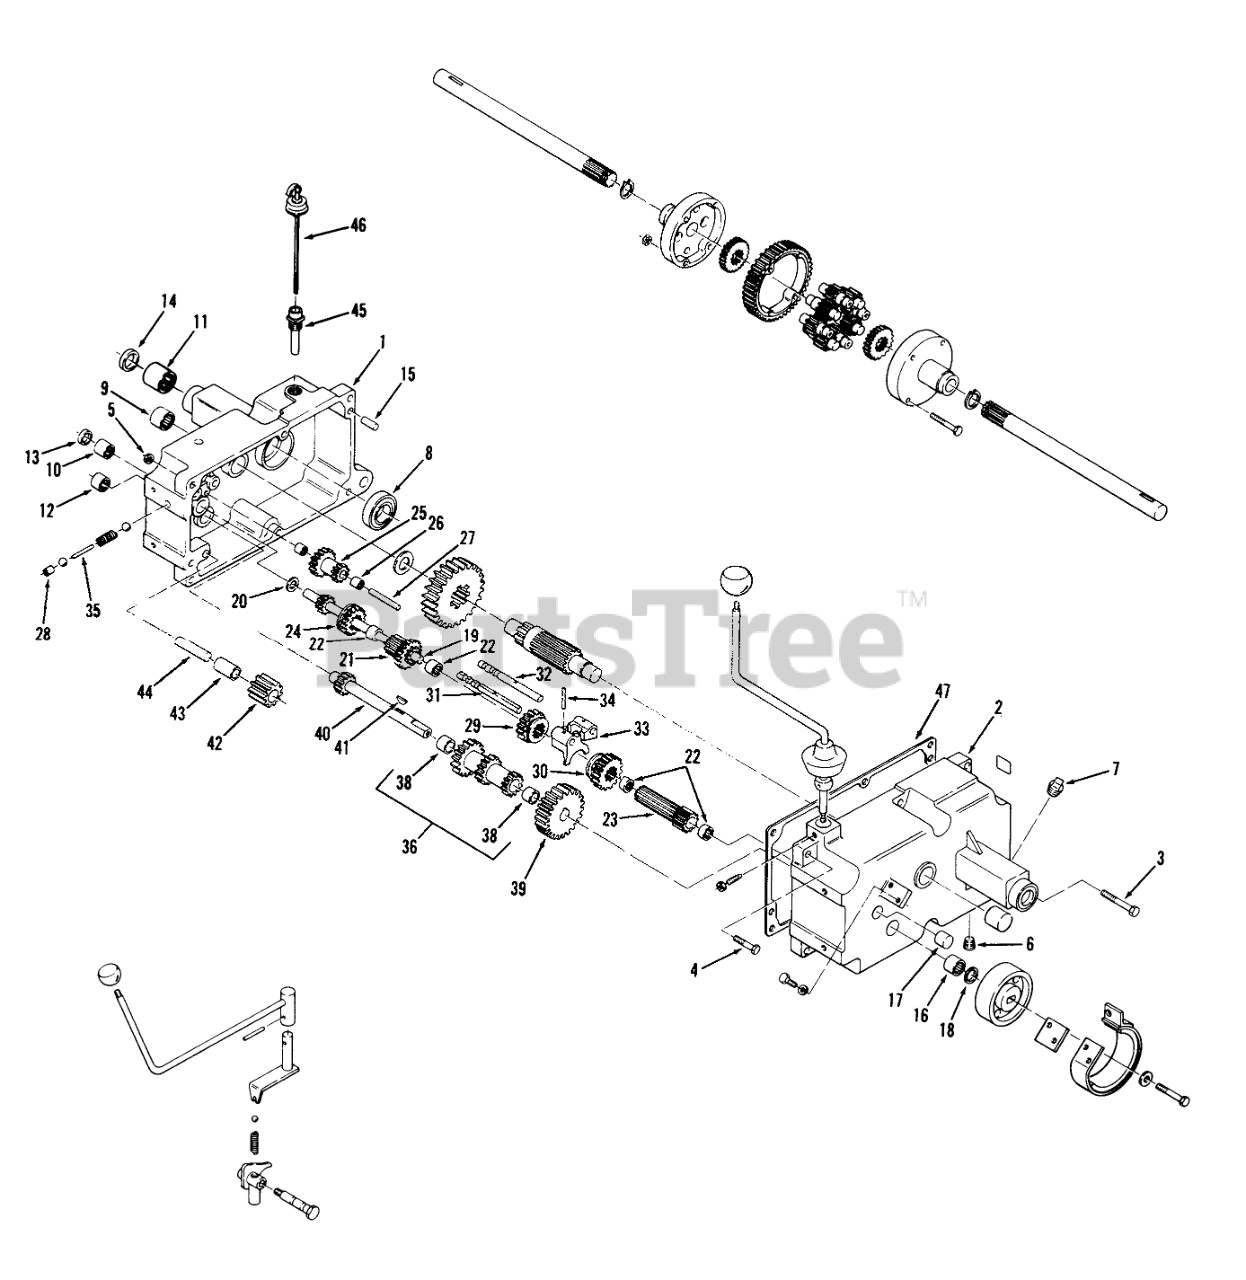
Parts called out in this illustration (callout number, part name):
1	Case RH
2	Case L.H.
3	HHCS
4	Bolt
5	Nut
6	PLUG 1/4 PIPE ALLEN
7	Plug
8	BALL BRG 1 1/2 I.D.
9	BEARING-NEEDLE
10	BEARING-NEEDLE
11	Bearing-Axle
12	BEARING-NEEDLE
13	SEAL-OIL
14	SEAL-OIL
15	PIN-DOWEL
16	BEARING-NEEDLE
17	Bearing Needle
18	SEAL-OIL
19	SHAFT-INPUT
20	WASHER-THR
21	GEAR
22	BEARING-NEEDLE
23	GEAR
24	GEAR-SLIDING
25	Gear
26	BEARING-NEEDLE
27	GEAR-SHAFT REDUCTION
28	CUP-PLUG
29	GEAR-HI AND 2ND
30	GEAR-LOW AND REVERSE
31	RAIL-SHIFT
32	RAIL-REAR SHIFT
33	FORK-SHIFT
34	PIN-ROLL
35	PIN-SHIFT
36	GEAR-CLUSTER
38	BUSHING-BRONZE
39	GEAR-CLUSTER SHAFT
40	Cluster Shaft
41	Key
42	GEAR/BUSHING ASM-REVERSE IDLER
43	BUSHING
44	PIN-DIFFERENTIAL
45	NIPPLE-FILL, TRANSMISSION
46	Dipstick
47	GASKET-TRANSMISSION
